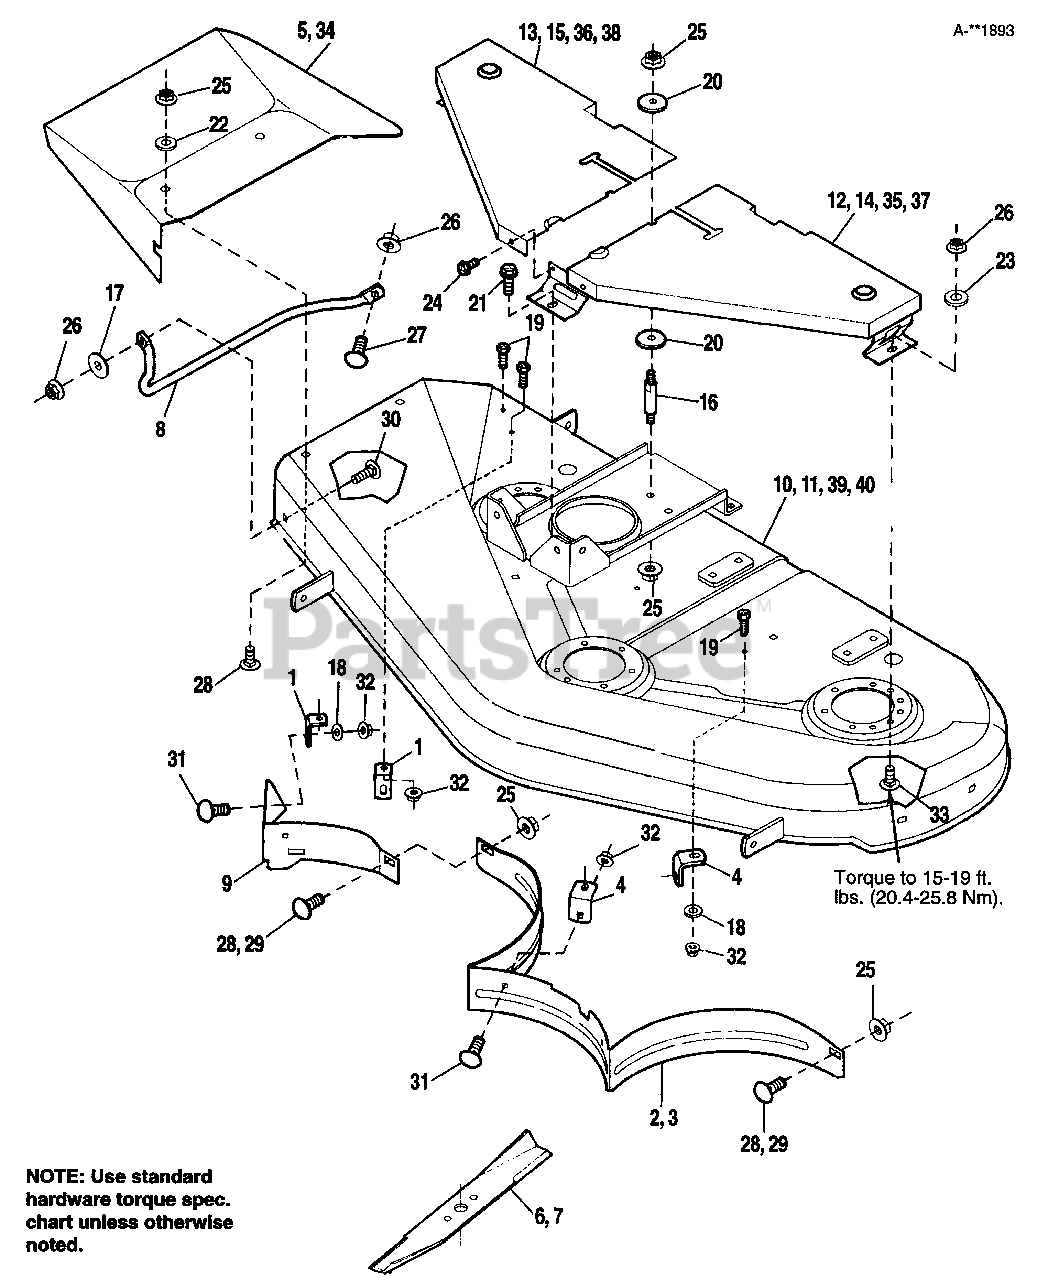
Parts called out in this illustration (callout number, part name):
1	CLIP, Baffle
2	BAFFLE, 42"
3	BAFFLE, 48"
4	CLIP, Baffle
5	DEFLECTOR, Orange
8	GUARD, Mower Discharge
9	BAFFLE, Discharge
10	HOUSING ASSY., 42", Orange
11	HOUSING ASSY., 48", Orange
12	COVER ASSY., Belt, LH, 48", Orange
13	COVER ASSY., Belt, RH, 48", Orange
14	COVER ASSY., Belt, LH, 42", Orange
15	COVER ASSY., Belt, RH, 42", Orange
16	STUD, Double Hex
17	WASHER, 5/16
18	WASHER, 1/4
19	CAPSCREW, Hex, 1/4-20 x 5/8
20	WASHER, 3/8
21	SCREW, Taptite, 5/16 x 1/2
22	WASHER, 3/8
23	WASHER, 3/8
24	SCREW, Taptite, 1/4-20 x 3/8
25	NUT, Hex, Whizlock, 3/8-16
26	NUT, Hex, Whizlock, 5/16-18
27	CARRIAGE BOLT, 5/16-18 x 3/4
28	CARRIAGE BOLT, 3/8-16 x 3/4 (Qty. 2 on 48")
29	CARRIAGE BOLT, 3/8-16 x 1, (48" deck only)
30	CARRIAGE BOLT, 5/16 x 1-1/4
31	CARRIAGE BOLT, 1/4-20 x 5/8
32	NUT, Hex, Whizlock, 1/4-20
33	SCREW, Taptite, 5/16-18 x 1
34	DEFLECTOR, Black
35	COVER ASSY., Belt, LH 48", Black
36	COVER ASSY., Belt, RH, 48", Black
37	COVER ASSY., Belt, LH 42", Black
38	COVER ASSY., Belt, RH, 42", Black
39	HOUSING ASSY., 42", Black
40	HOUSING ASSY., 48", Black
